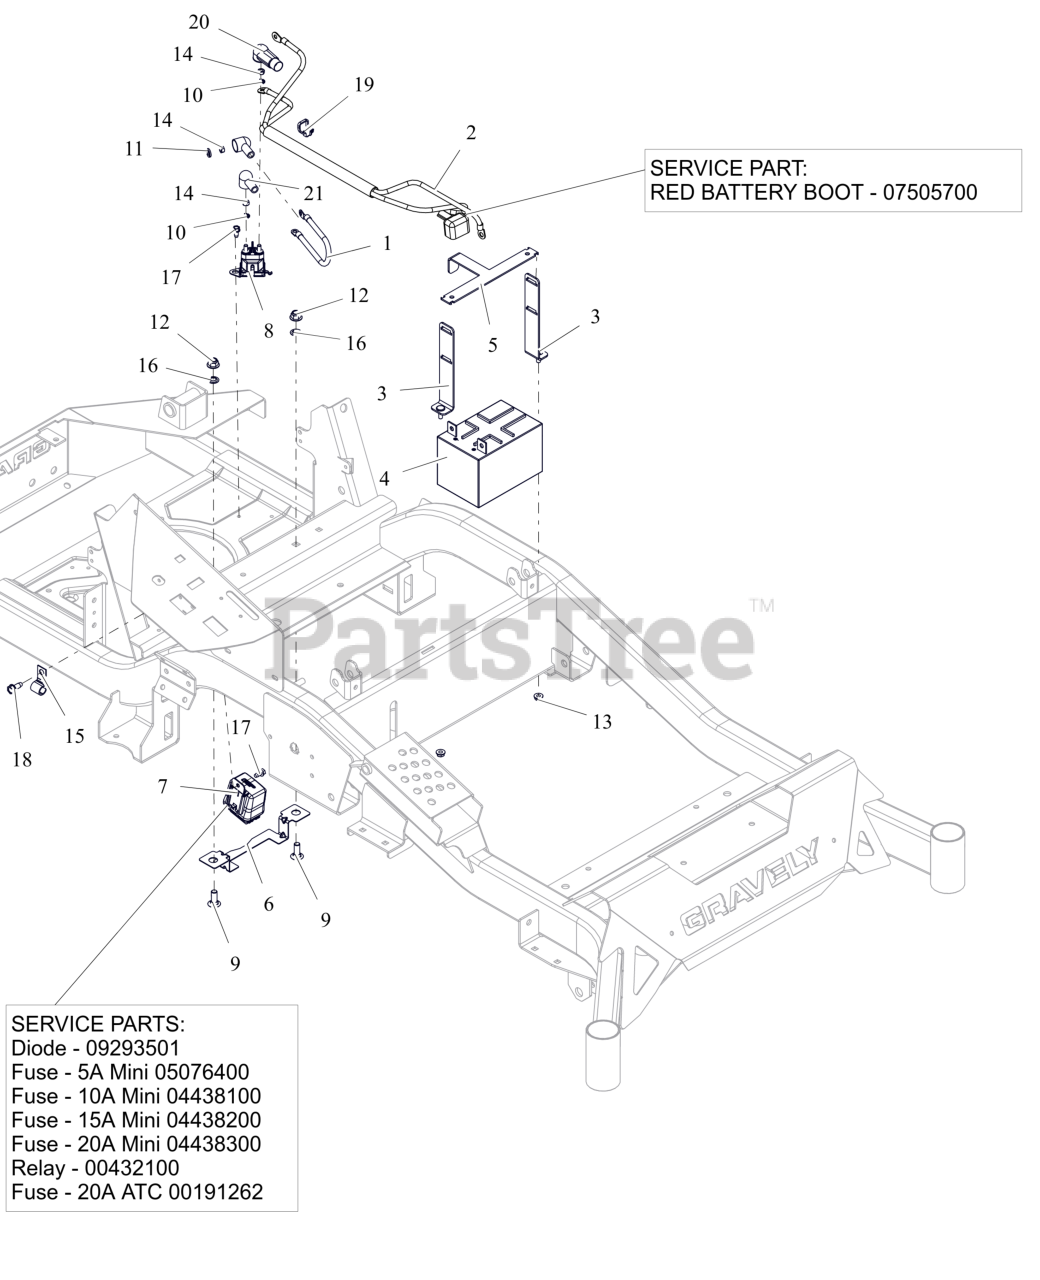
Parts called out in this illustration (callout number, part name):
1	CABLE, POS W/(2)1/4 RING 9.0LG
2	HARNESS, BATTERY HD
2	INSULATOR
3	WMT,BATTERY MOUNT HOLD DOWN
4	BATTERY, 12V 12A-190CCA
5	BRKT, BATTERY TIE DOWN
6	GUARD, ELECTRICAL HARNESS
7	HARNESS, WIRE
7	DIODE, CONNECTOR SHELL
7	FUSE, 5 AMP MINI-ATC
7	FUSE,10 AMP MINI-ATC
7	FUSE,15 AMP MINI-ATC
7	FUSE,20 AMP MINI ATC
7	RELAY,SEALED W/DIODE
7	FUSE, 20 AMP BLADE S/O
8	SOLENOID, STARTER (SEALED)
9	BLT, RHSN .38-16X1.00 G5 ZCC
10	WSHR,LK-EXT.262X.502X.026 ZCC
11	WSHR,LK-REG .312X.078 ZCC
12	NUT,NYL-FLG .38-16 GF ZCC
13	NUT-LK-TOP-FLG .250-20 GF ZCC
14	NUT-STD M6-1.0 ZCC
16	NUT-PUSH .38 DIA. PAL ZINC
17	SCR-TAP .25-20X.50 HWH ZCC
18	SCR,TAP .312-18X.75 HWH TR ZCC
19	CABLE TIE W/ TREE (.25 HOLE)
20	BOOT, .65ID POS
21	BOOT, EYELET TERMINAL
